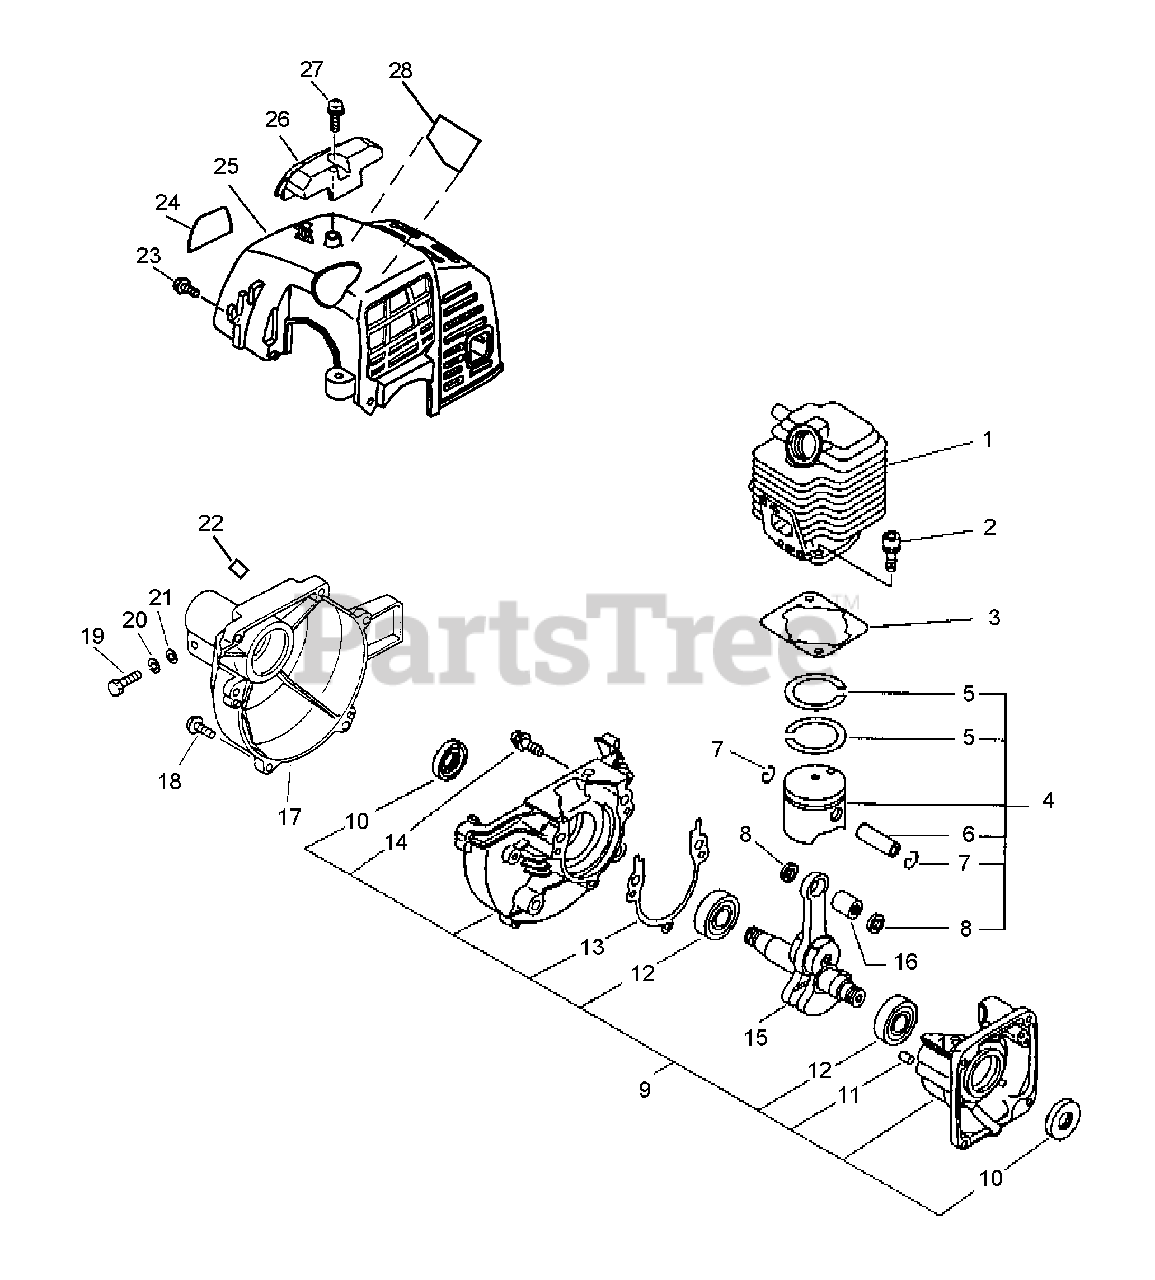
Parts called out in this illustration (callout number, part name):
1	CYLINDER
2	SCREW - 5X22
3	GASKET, CYLINDER
4	PISTON KIT
5	RING, PISTON
6	PIN, PISTON
7	RING, RETAINING
8	SPACER, PISTON
9	CRANKCASE ASSY
10	SEAL, OIL
11	PIN - LOCATING
12	BEARING, BALL - 6201
13	GASKET, CRANKCASE
14	SCREW - 5X28
15	CRANKSHAFT ASSY
16	BEARING, NEEDLE
17	CASE, FAN
18	SCREW - 4X18
19	BOLT - 5X28
20	LOCKWASHER - 5
21	WASHER - 5
22	NUT - 5 -- SQUARE
23	SCREW - 4X12 -- TAPPING
24	LABEL - MODEL
25	COVER, ENGINE - ORANGE
26	GUARD, TOP - BLACK
27	SCREW - 5X16 -- TAPPING
28	LABEL - CAUTION
